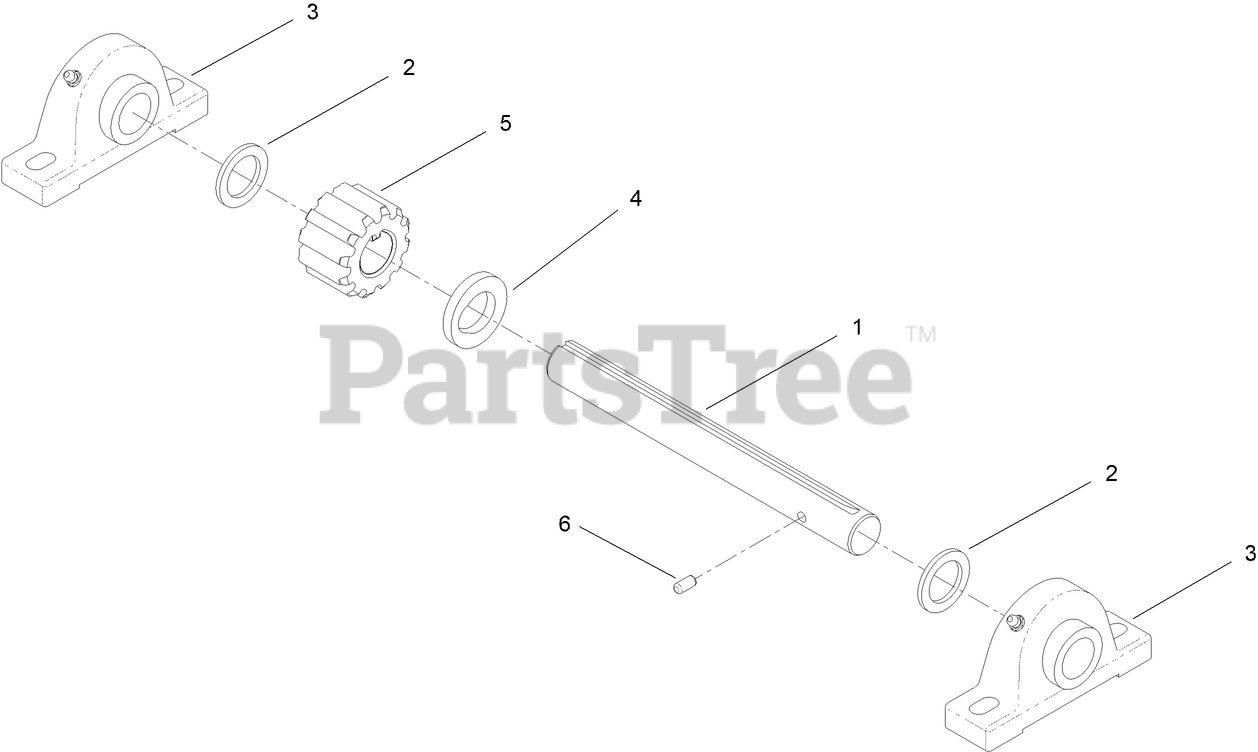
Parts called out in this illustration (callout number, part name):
2	WASHER-THRUST
3	BEARING-BLOCK, PILLOW
4	WASHER
5	GEAR-SPUR
6	PIN-DOWEL
